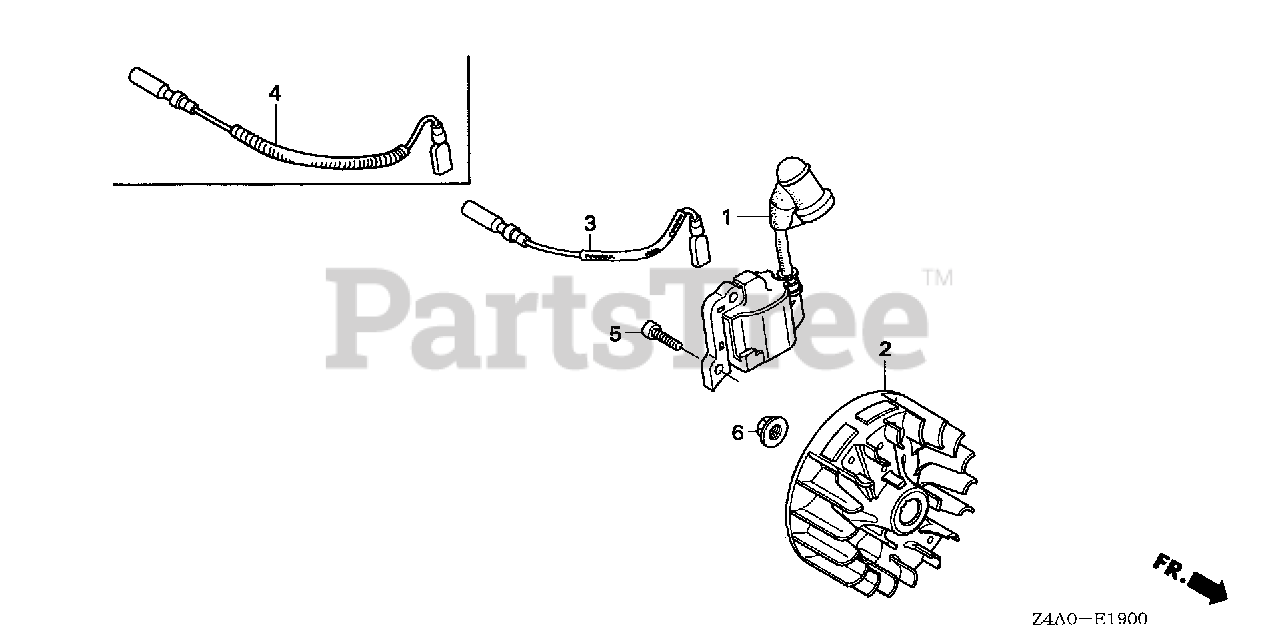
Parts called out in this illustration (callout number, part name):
1	COIL ASSY., IGNITION
2	FLYWHEEL
4	WIRE, STOP SWITCH
5	BOLT, SOCKET (4X14)
6	NUT, FLANGE (7MM)
